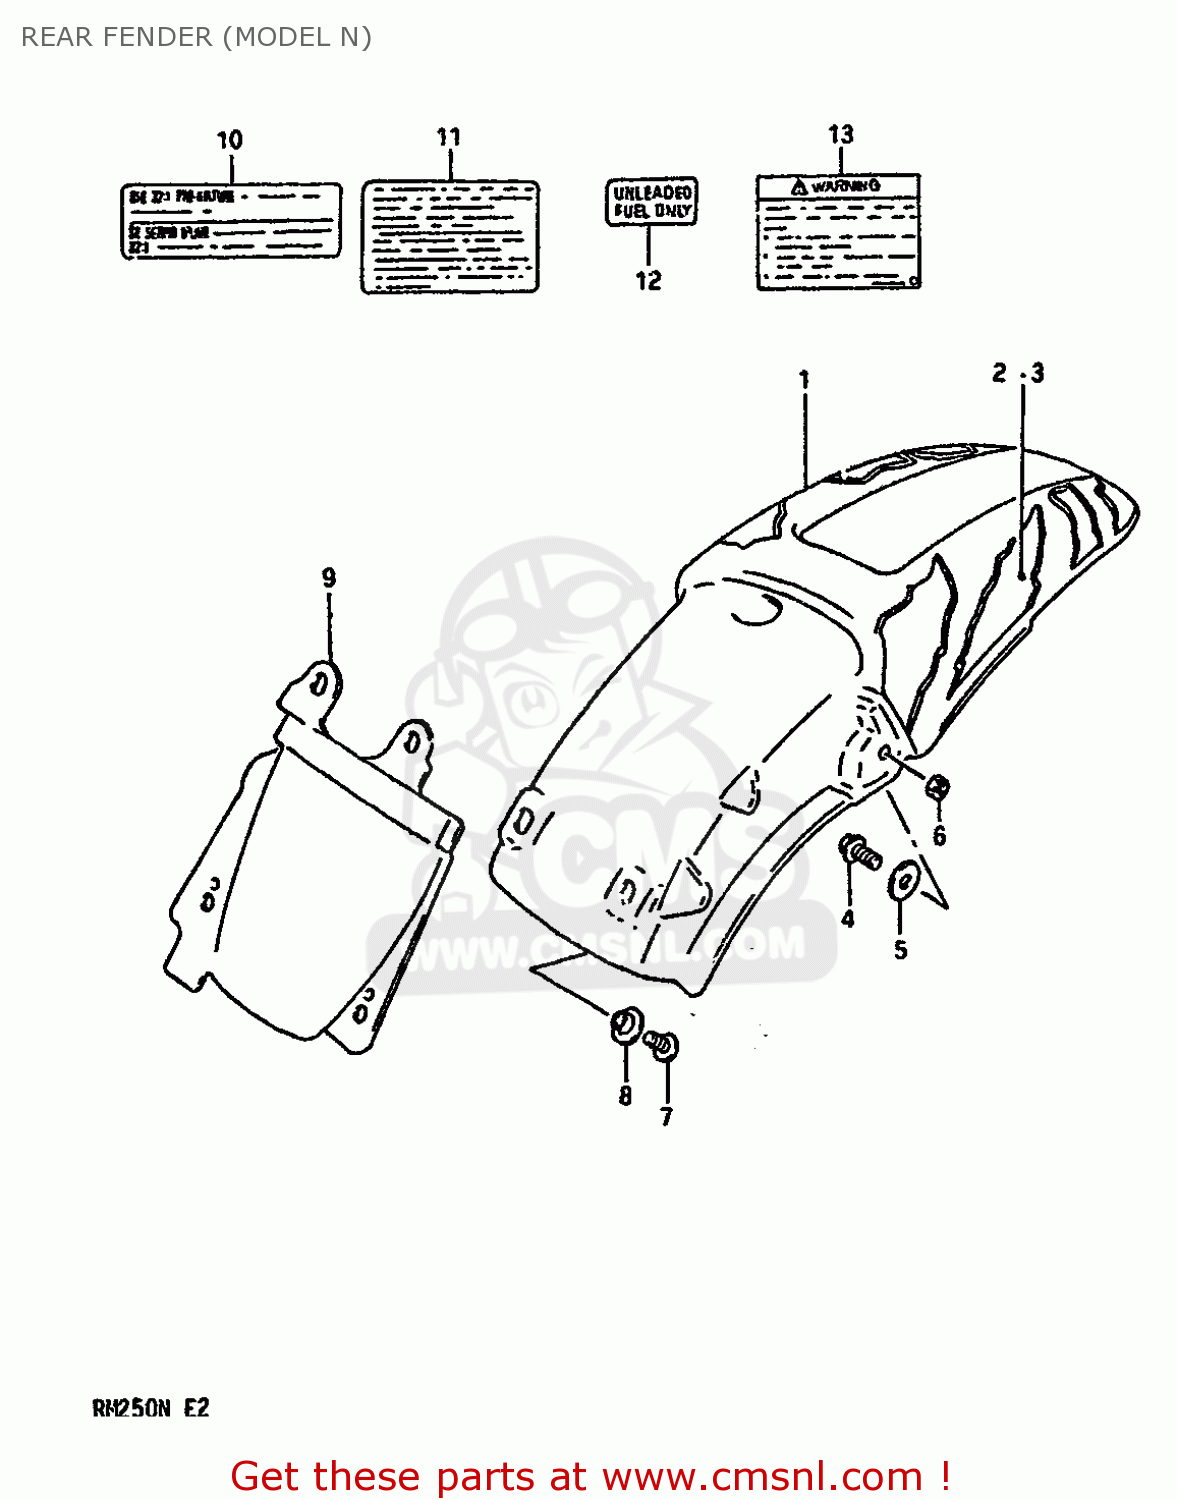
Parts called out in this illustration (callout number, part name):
1	BODY,RR FENDER
2	EMBLEM,FENDER RH
3	EMBLEM,FENDER LH
4	BOLT
5	WASHER (6.5X29X1.6)
6	NUT 6MM
7	SCREW
8	WASHER
9	MUD GUARD,REAR FENDER,FRONT
10	LABEL,WARNING
11	LABEL
12	LABEL,UNLEADED FUEL
13	LABEL
